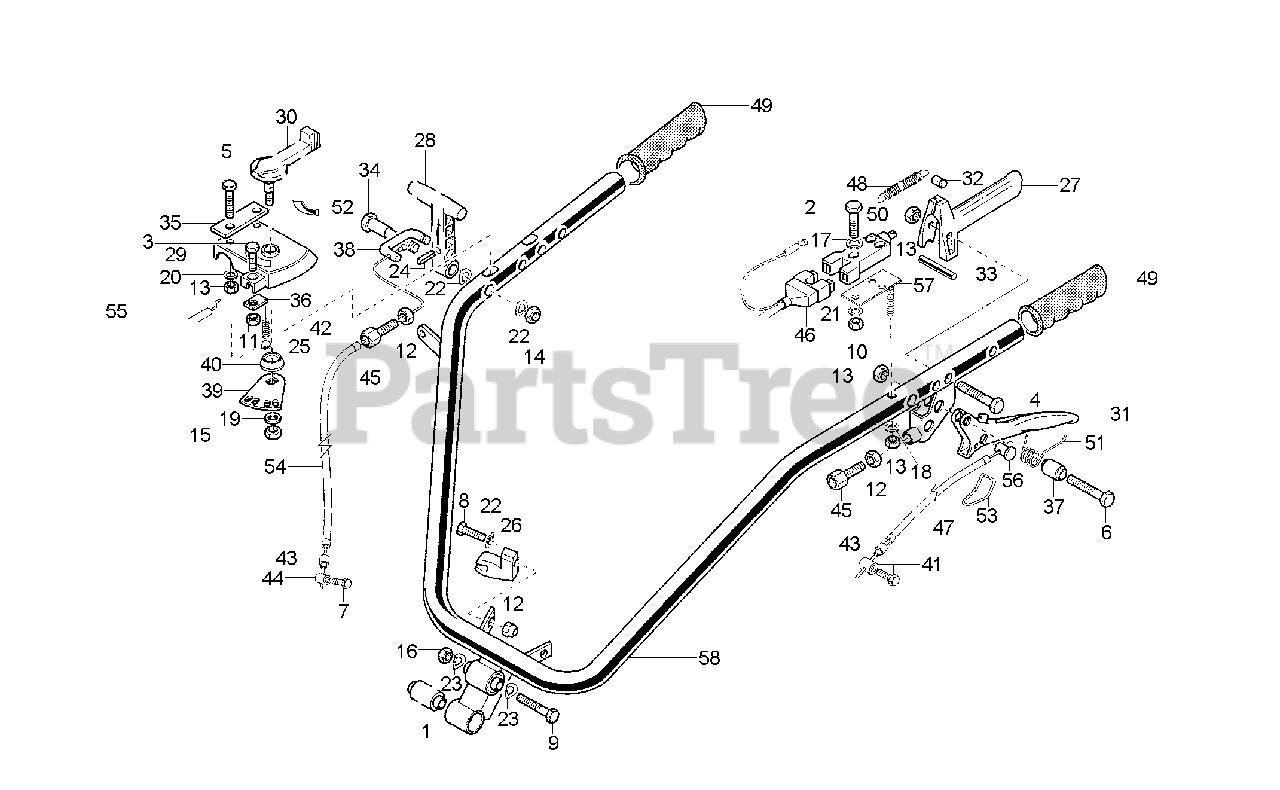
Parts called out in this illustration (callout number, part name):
1	SILENTBLOCK
2	SCREW TE M4X25
3	SCREW, M5X10
4	SCREW, TE M6X45
5	SCREW, M6X50
6	SCREW, M6X25
7	SCREW, TE M6X16
8	SCREW, M8X35
9	SCREW, M10X80
13	NUT, SELF LOCKING M6
17	FLAT WASHER, M4.3
18	WASHER, FLAT M6.3
19	WASHER, M8.4
20	LOCK WASHER, M6.4
21	LOCK WASHER, M4.3
22	LOCK WASHER, M8.4
23	WAVE WASHER, M10.4
24	PIN, LOCKING, M4X20
26	SUPPORT, CONTROL ROD
27	MOTOR STOP LEVER
28	REVERSER LEVER
30	THROTTLE LEVER
31	CLUTCH LEVER
33	LEVER STOP FOR MOTOR STOP
37	LEVER SPACER
39	THROTTLE LEVER
41	CLAMP, CABLE
44	PIN, CABLE CLAMP
45	SCREW, ADJUSTING, M8
46	SWITCH WIRING HARNESS
47	CLUTCH CABLE
50	STOP SWITCH
51	LEVER SPRING
52	THROTTLE DECAL
54	REVERSER CABLE
55	THROTTLE CABLE
57	SWITCH PLATE
